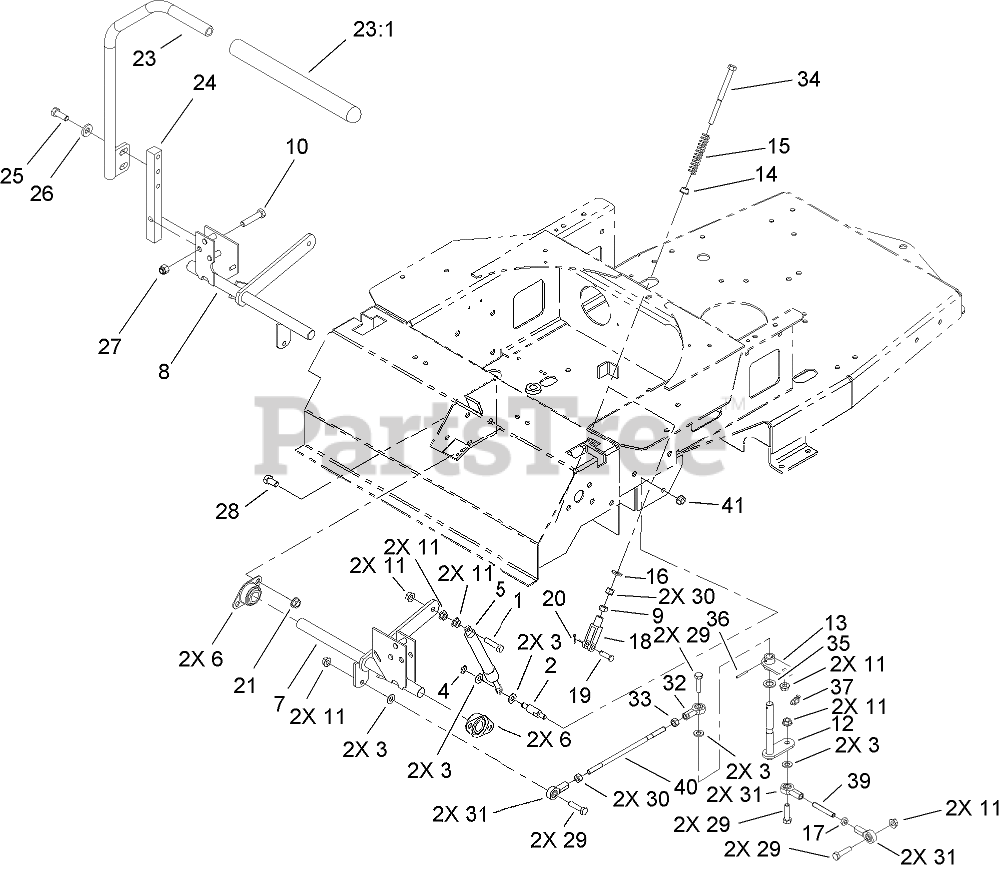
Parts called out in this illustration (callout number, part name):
1	SCREW-HH
2	PIN-DAMPER
3	WASHER-PLAIN
4	RING-RETAINING, EXT
5	Damper-Control, Motion
6	BEARING-FLANGE, SIDE
7	BRACKET-MOTION CONTROL, LH
8	BRACKET-MOTION CONTROL, RH
9	NUT-LOCK
10	SCREW-HH
11	NUT-HF
12	PIVOT ASM
13	PIVOT PLATE ASM
14	BUSHING-FLANGED
15	SPRING-RETURN, NEUTRAL
16	WASHER-FLAT
17	NUT-JAM
18	YOKE-ADJUSTABLE
19	PIN-CLEVIS
20	PIN-COTTER
21	NUT-HHF, WHIZ
23	RH LEVER ASM
23:1	GRIP-CONTROL, MOTION
24	ARM-SHAFT, CONTROL
25	SCREW-HH
26	WASHER-BELLEVILLE
27	NUT-LOCK, NI
28	SCREW-HH
29	SCREW-HH
30	NUT-HEX
31	BALLJOINT-RH
32	BALLJOINT-LH
34	BOLT-RETURN, NEUTRAL
35	WASHER
36	PIN-ROLL
37	FITTING-LUBE, 45 DEG
39	LINKAGE-LOWER, LH
40	LINKAGE-UPPER
41	NUT-HF
